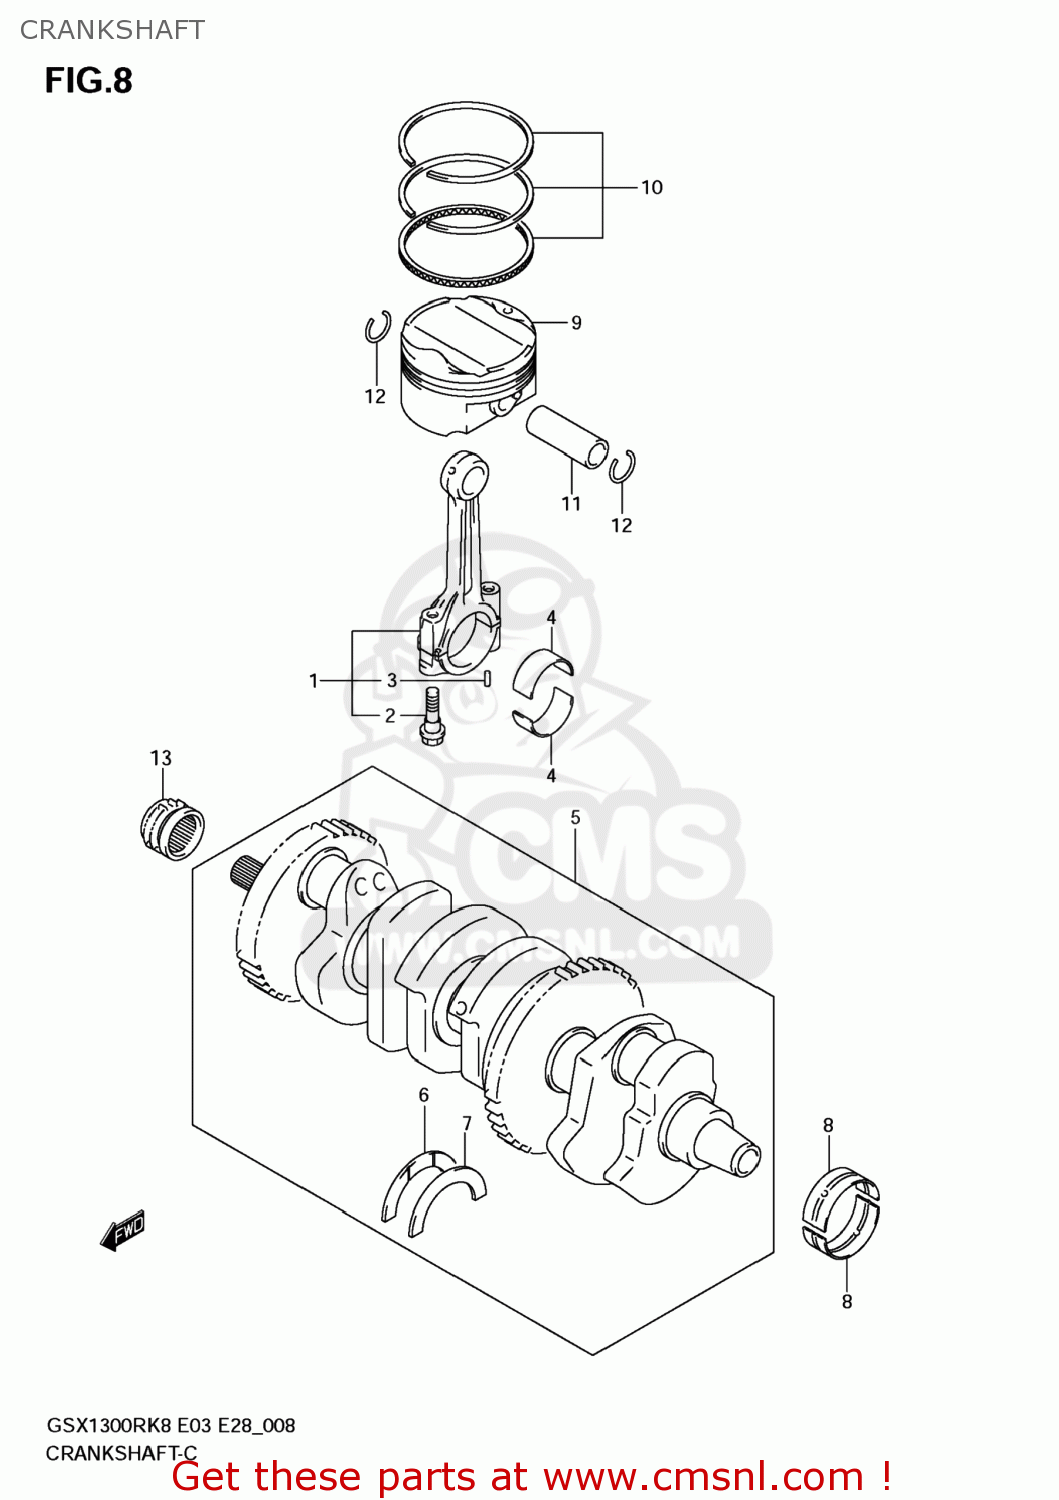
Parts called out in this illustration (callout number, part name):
1	CONNECTING ROD ASSY
2	BOLT,CONNECTING ROD
3	PIN
4	BEARING,CRANK PIN
5	CRANKSHAFT SET
6	BEARING,CRANK THRUST,L
7	BEARING,CRANK THRUST,L
8	BEARING,CRANKSHAFT
9	PISTON
10	RING SET,PISTON
11	PIN,PISTON
12	CIRCLIP
13	SPROCKET,CAM CHAIN DRIVE
